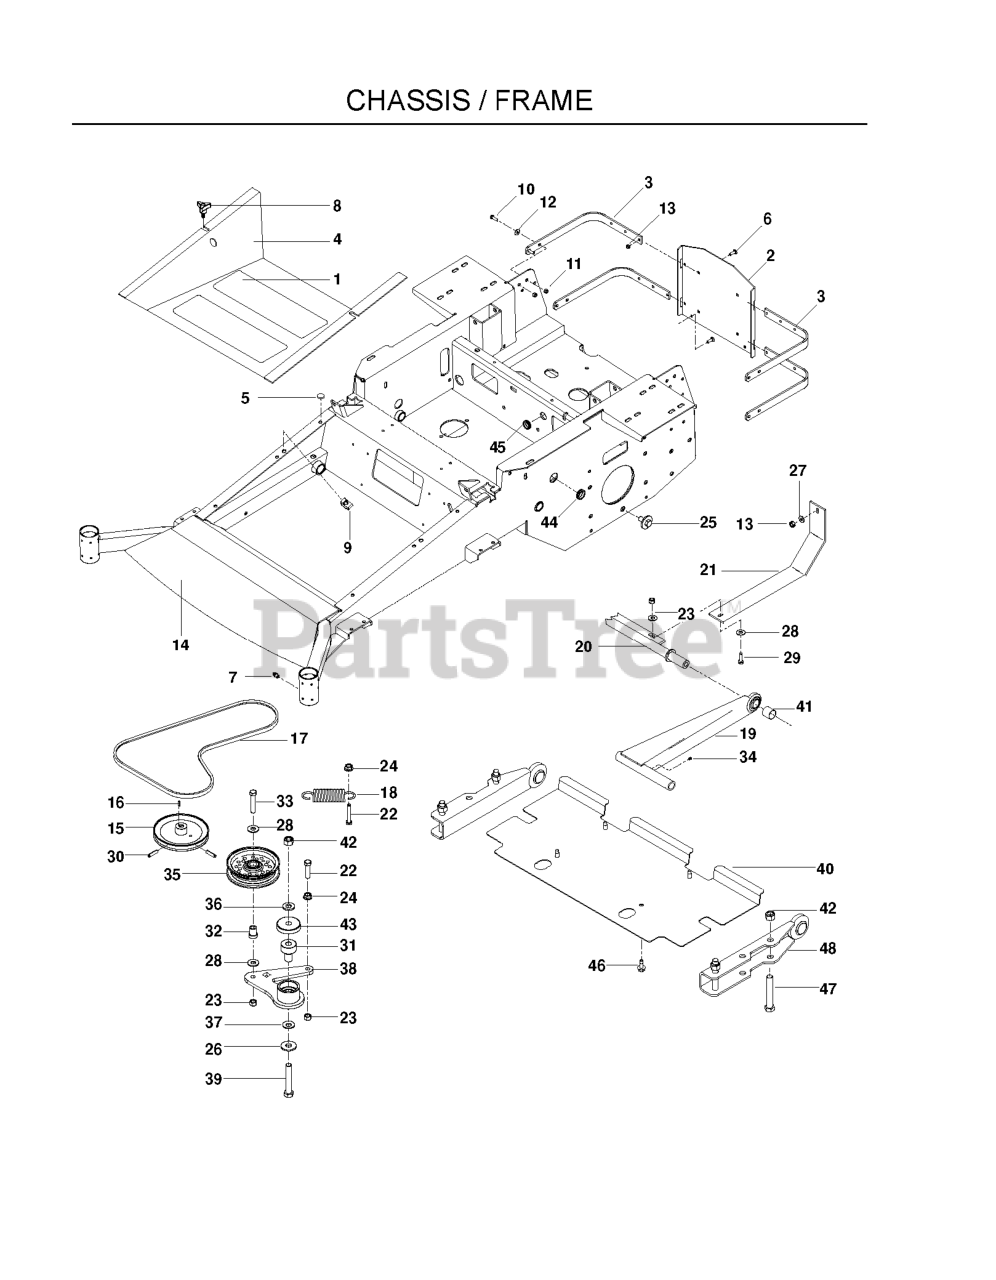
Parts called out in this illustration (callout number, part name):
1	ANTI-SKID PAD
2	XP GUARD, BLACK
3	ENGINE SHROUD BRKT
4	FOOT PLATE WIDMT
5	GROMMET, BUMPER
6	BOLT 5/16C X 3/4" CARRIAGE
7	ZERK
8	KNOB W/STUD
9	U-CLIP 5/16-18 NUT RETAINER
10	HCS 5/16C X 1
11	NUT 5/16 NYLOC
12	WASHER 5/16 FLAT
13	NUT 5/16C CENTERLOCK
14	FRAME W/DECALS 52/61
16	KEY 5 MM SQ X 25 MM
17	BELT, PUMP
20	CROSS SHAFT, STRUT - BLK
21	SKID PLATE
22	HCS 3/8C X 1 1/2
23	NUT 3/8-16 NYLOC
24	NUT 3/8C WHIZ
25	BLADE BOLT/WASHER
26	WASH USS FLAT 1/2
27	WASHER 5/16 FLAT
28	WASHER 3/8 FLAT
29	HCS 3/8-16X1.GRD.5.ZD
30	5/16 DIA ROLL PIN
31	PIVOT, BEARING
32	BUSHING, IDLER FLANGE
33	HCS 3/8C X 2
34	ZERK
35	IDLER PULLEY
36	WASHER 1/2" FLAT
37	CONTACT BELLSPR 1/2
38	ARM, IDLER - W/BEARINGS
39	SCREW, 1/2C X 3 HEX CAP
40	REAR DEBRIS SHIELD
41	SPACER, STRUT
42	NUT 1/2-13 HEX NYLOC ZD
43	SHIELD, DUST
44	RUBBER GROMMET
45	GROMMET, FUEL LINE
46	BOLT 5/16-18 X 3/4
47	HCS 1/2C X 3 1/4
48	STRUT WELDMENT, REAR
